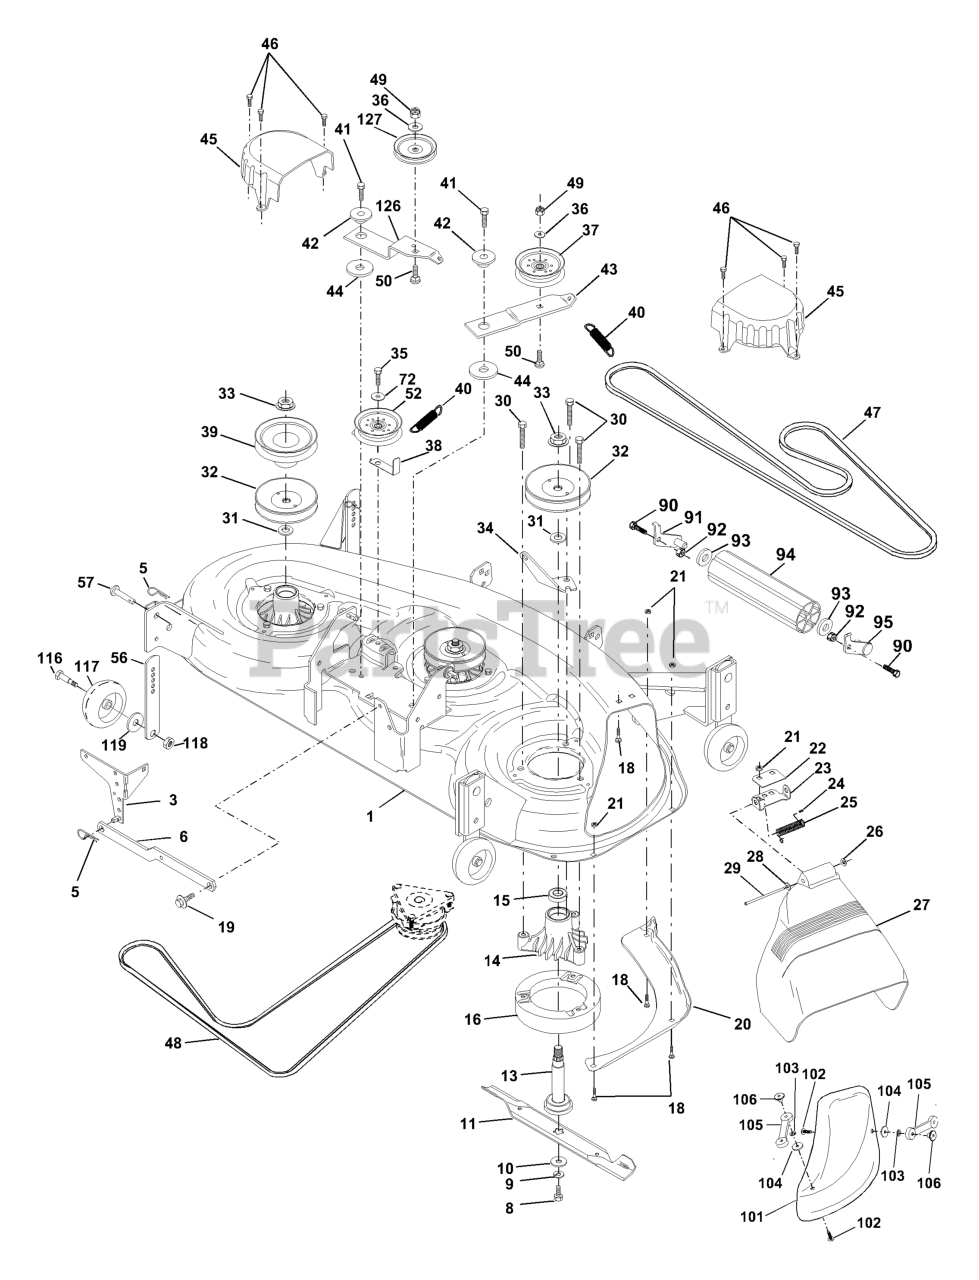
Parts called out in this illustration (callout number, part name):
1	DECK SVC W/ADJ.GWB.46"
3	BRACKET SWAY BAR
5	RETAINER-SPRNG RB
6	REAR SUSP ARM
8	BLADE BOLT
9	LOCKWASHER
10	WASHER.BLADE
11	BLADE.46".HI-LIFT.PREMIUM
11	MULCH BLADE 46"
13	SHAFT.ASM.W/BEARING
14	HOUSING.MANDREL.44/46" VENT
16	STRIPPER.MANDREL.ROUND.BLACK
18	BOLT
19	BOLT SHD 5/16-18
20	BAFFLE, VORTEX MOWER 46"
21	LOCKNUT
22	BRKT, STIFF 42" DECK
23	BRKT, DEFLECTOR MOWER 42"
24	CAP-SLEEVE LT
25	TORSION SPRING
26	NUT PUSH M
27	SHIELD DEFLECTOR
28	Washer 11/32 x 5/8 x 16 Ga.
29	ROD.HINGE
30	SCREW THDROL ROLLING WASHER HD
31	WASHER
32	MANDREL PULLEY
33	NUT
34	ANCHOR SPRING, DECK 46"
35	SCREW LT
36	WASHER
37	PULLEY.IDLER.FLAT
38	REPL BY 532 1560-86
39	REPL BY 532 1449-17
40	SPRING.SEC.44"VEN
41	SCREW.3/8-16
42	SPACER RETAINER
43	ARM, IDLER, SECONDARY
44	HARDENED WASHER
45	COVER MANDREL 46
46	SCREW.1/4-20X5/8
47	BELT V SECONDARY
48	V-BELT PRIMARY 50"
50	BOLT.3/8-16X1.50
52	PULLEY.IDLER.FLAT.46".PRIMARY
56	BAR.ADJUST.WHEEL.ANTI.SCALP.BL
57	RIVET.PIN.HEAD.YELLOW.
72	WASHER
90	BOLT
91	BRACKET LH (A)
92	NUT
93	Washer 17/32 x 7/8 x 16 Ga.
94	NOSE ROLLER
95	BRACKET RH (B)
101	COVER.MULCH.46"3-BLADE.(2 2)
102	SCREW
103	LOCKWASHER #10
105	LATCH ASSY
106	WELDNUT
116	BOLT, SHOULDER
117	WHEEL GAGE DONUT
118	LOCKNUT
119	WASHER.5/16.FLAT.STE.STD.
126	ARM, IDLER PRIMARY DECK
127	REPL BY 532 1467-63
